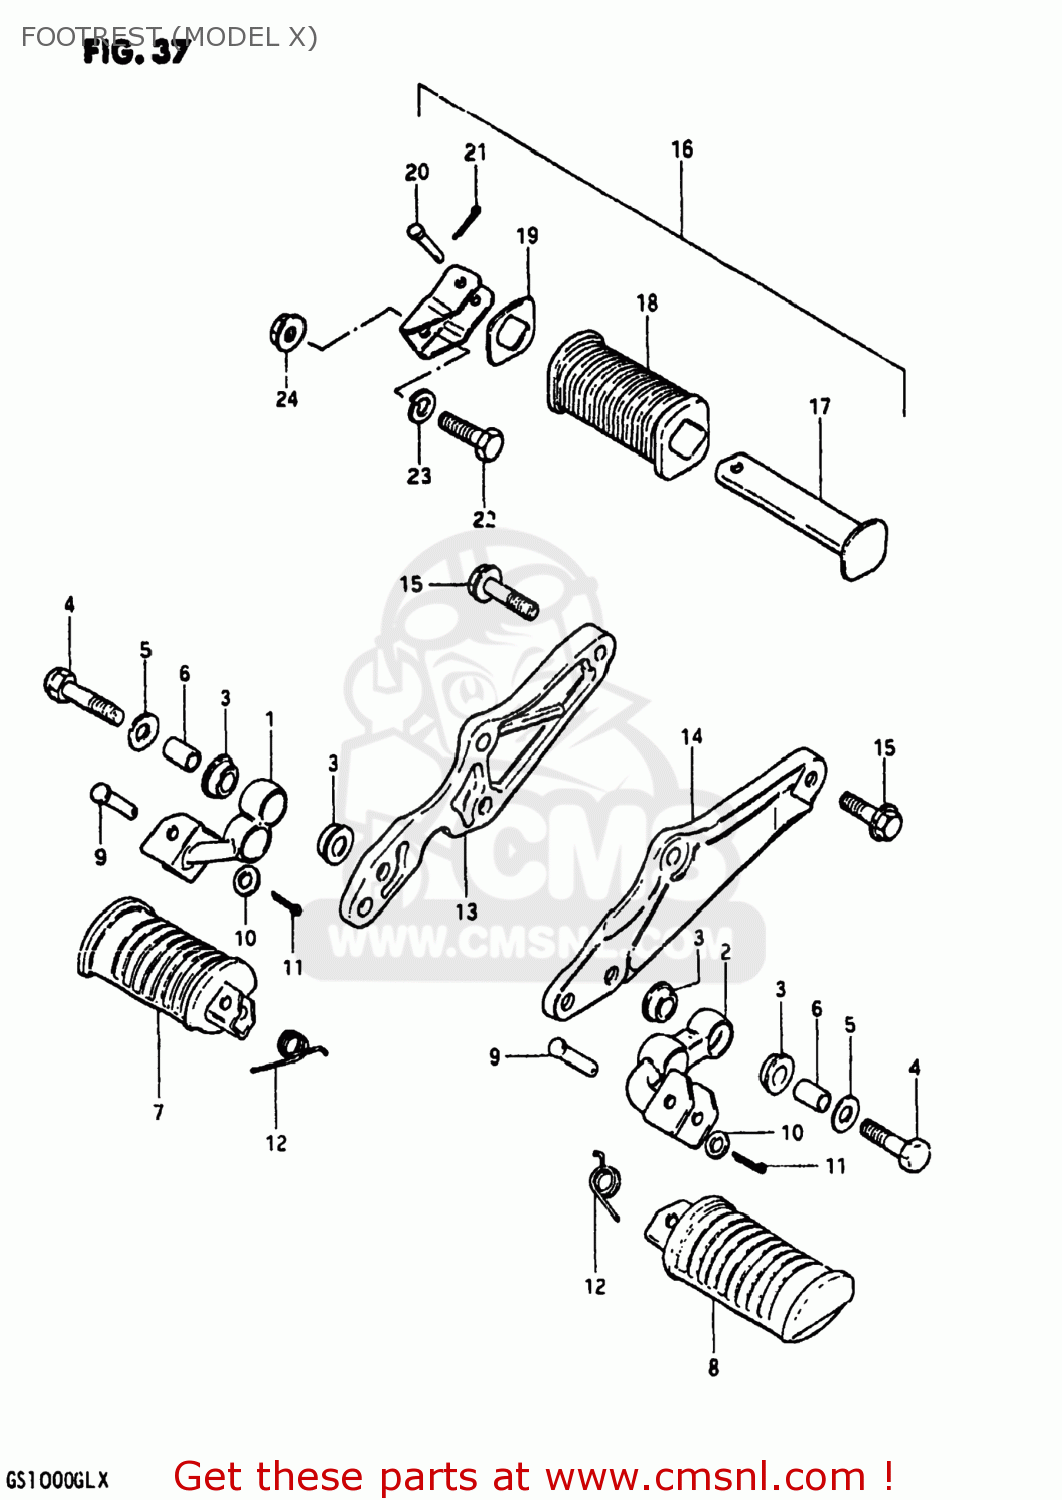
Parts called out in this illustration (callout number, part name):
1	BAR,FRONT FOOTREST
2	BAR,FRONT FOOTREST,LEFT
3	BUSH
4	BOLT(10X50)
5	WASHER(10.5X28X2.3)
6	SPACER (10.2X14X20)
7	RUBBER,FRONT FOOTREST
8	FOOTREST
9	PIN
10	WASHER
11	PIN
12	SPRING
13	BRACKET
14	BRACKET
15	BOLT
16	FOOTREST ASSEMBLY,PILLION
17	BAR,REAR FOOTREST,LEFT
18	RUBBER,PILLION FOOTREST
19	WASHER,FOOTREST RUBBER
20	PIN
21	PIN
22	BOLT,M10X1.25X
23	LOCK WASHER
24	NUT
